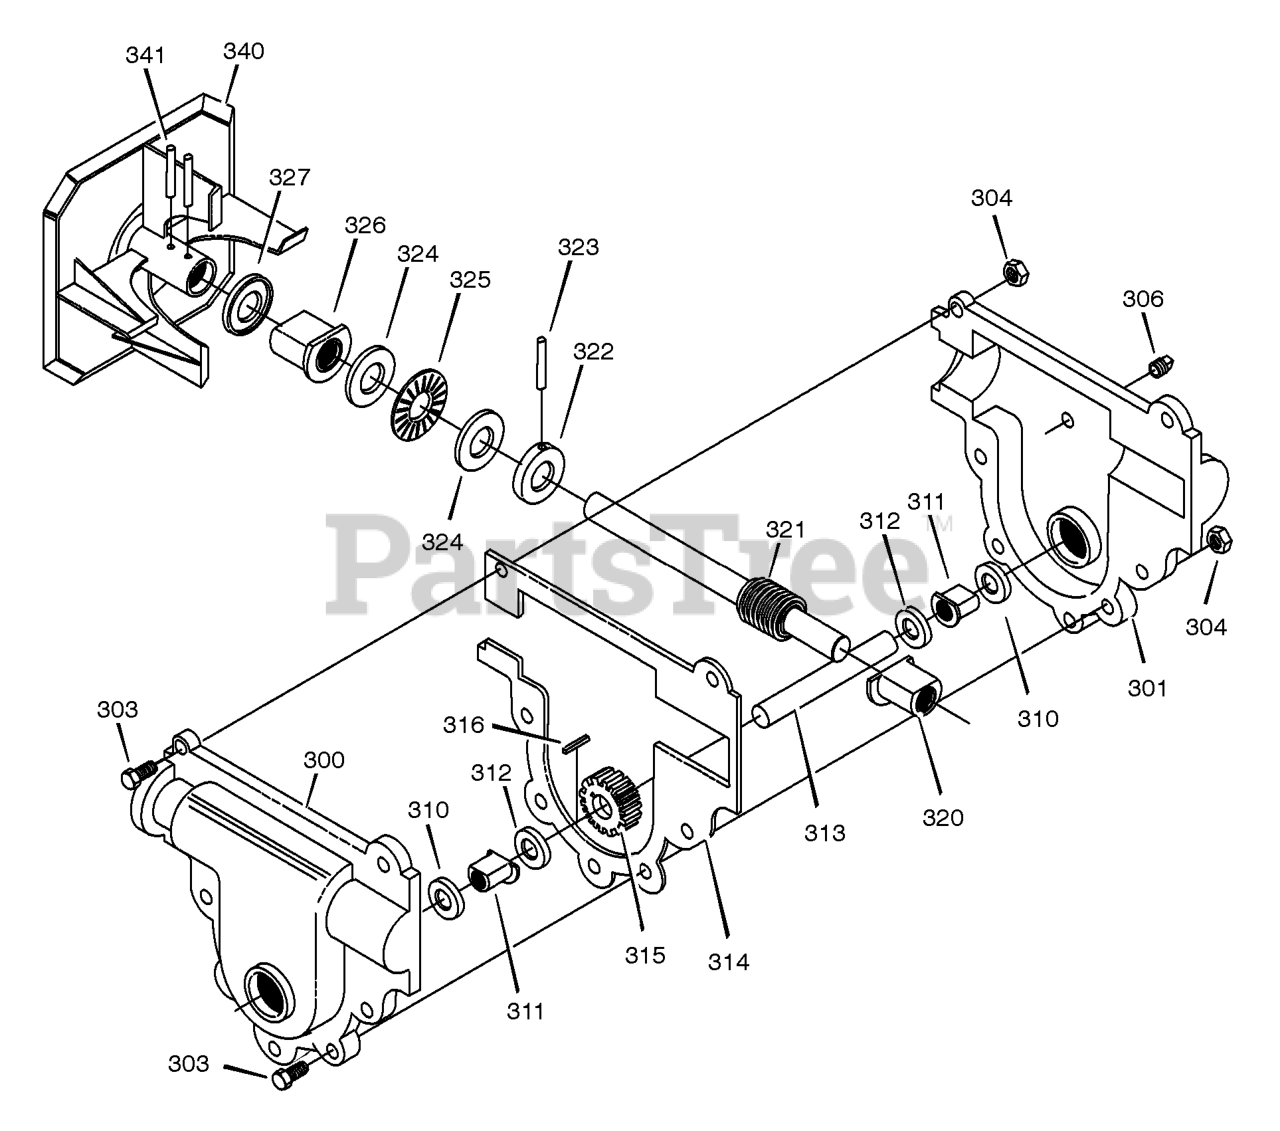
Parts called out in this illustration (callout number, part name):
300	CASE, GEAR, RH
301	CASE, GEAR, LH
303	SCREW,1/4-20X.75
304	NUT,1/4-20
306	SCREW, 3/8-16 x 0.50
310	SEAL, OIL
311	BEARING, FL
312	WASHER, FLAT
313	SHAFT, AUGER OUTPUT
314	GASKET, GEAR BOX
315	GEAR, WORM
316	KEY, WOODRUFF #61
320	BRNG, FL
321	SHAFT, AUGER INPUT (IMPELLER)
322	COLLAR, THRUST
323	PIN, SPRING
324	WASHER, FLAT
325	BRNG, ROLL
326	BRNG, FL
327	SEAL, OIL
341	PIN, SPRING
